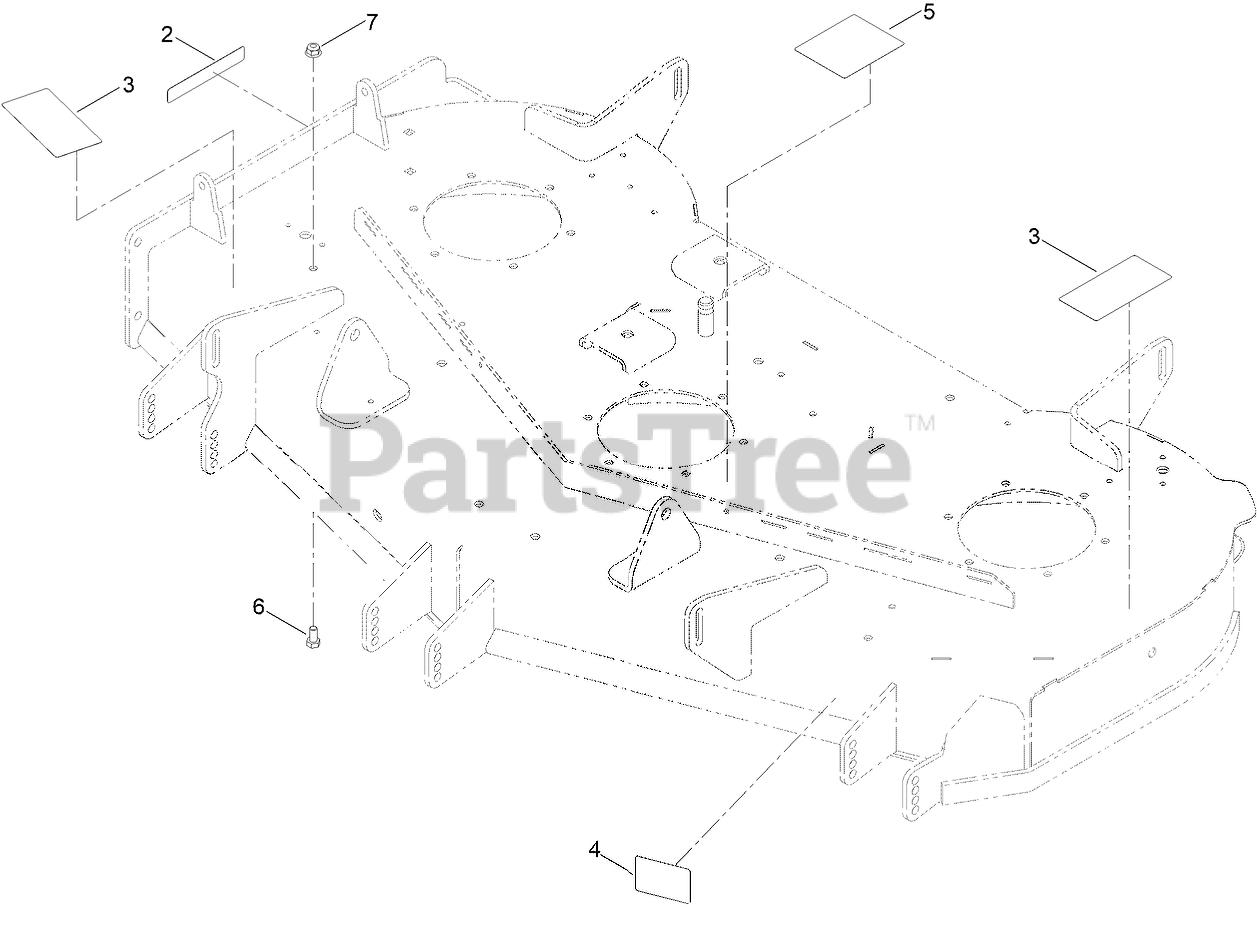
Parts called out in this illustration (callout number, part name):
2	DECAL-DANGER
3	DECAL-DANGER, DECK
4	DECAL-SCALP, ANTI
5	DECAL-ROUTING, BELT
6	SCREW-HH
7	NUT-HF, NI
